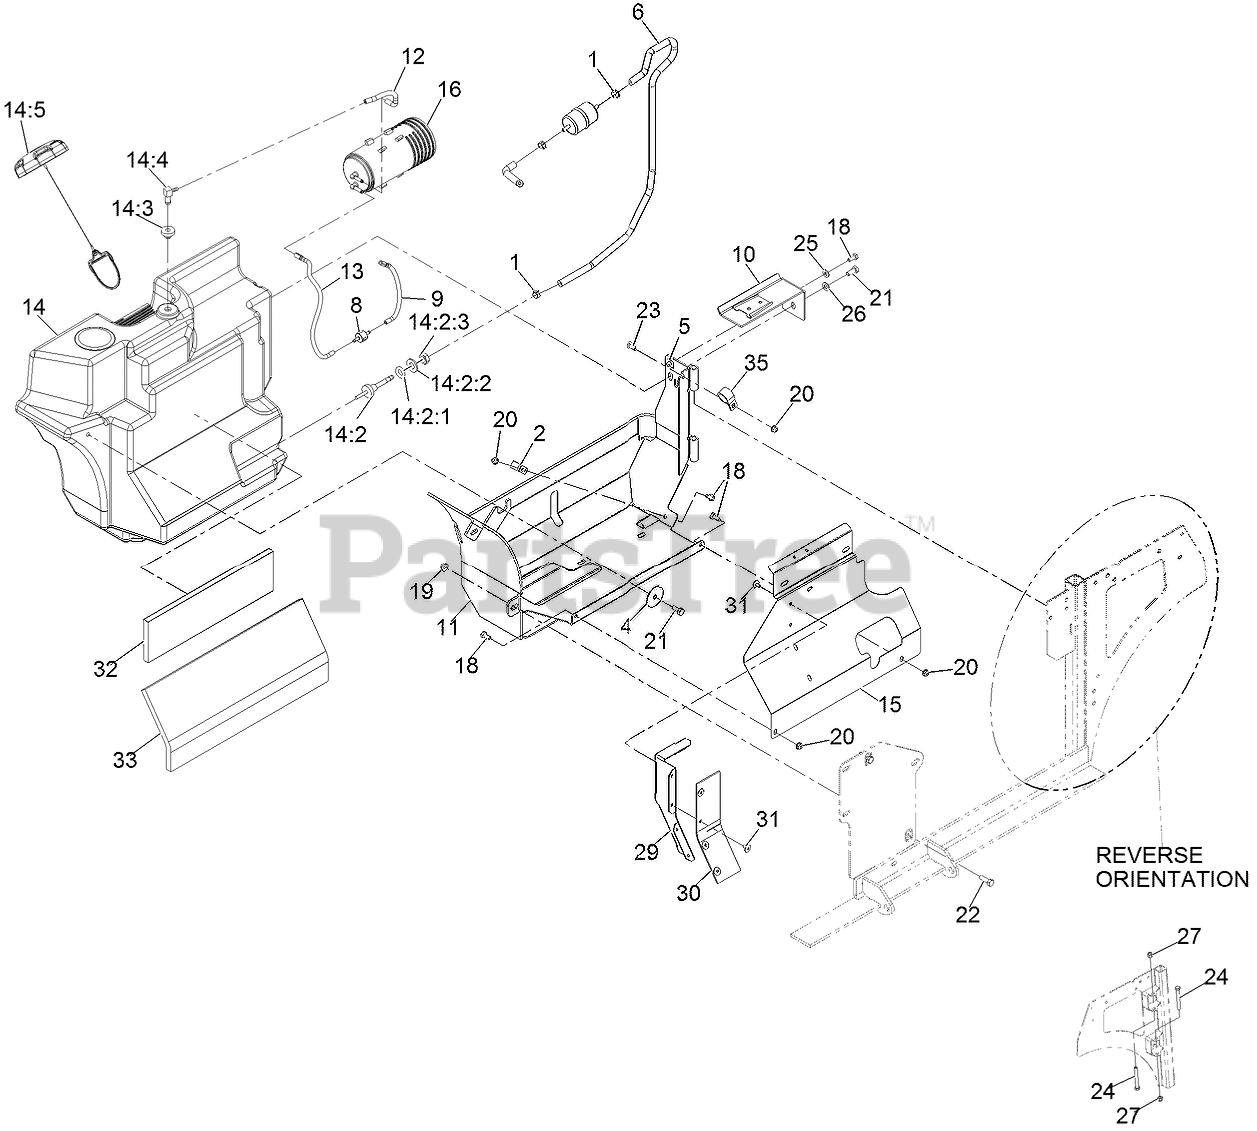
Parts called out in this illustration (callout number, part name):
1	CLAMP-HOSE
2	CLIP-LOOM
6	FUEL LINE ASM
8	VALVE-CHECK, VACUUM
9	HOSE-VENT, FORMED
10	CANISTER BRACKET ASM
11	TANK FRAME ASM
12	HOSE-VENT, FORMED
13	HOSE-VENT, FORMED
14	FUEL TANK ASM
14:2	FITTING-FUEL, BULKHEAD
14:2:1	O-RING,BULKHEAD FITTING
14:2:2	WASHER-FLAT
14:2:3	NUT-JAM
14:3	BUSHING
14:5	CAP-FUEL, RATCHETING
15	PANEL-TANK SHIELD
16	CANISTER-CARBON, 800CC
18	SCREW-HH
21	SCREW-HH
22	SCREW-HH
23	BOLT-CARR
24	SCREW-HH
25	WASHER-FLAT
26	WASHER-PLAIN
27	NUT-LOCK, NI
29	DEFLECTOR-AIR
30	FLAP-RUBBER
31	RIVET-POP
32	INSULATION-FOAM PAD, FRON
33	INSULATION-FOAM PAD, REAR
35	R-CLAMP
